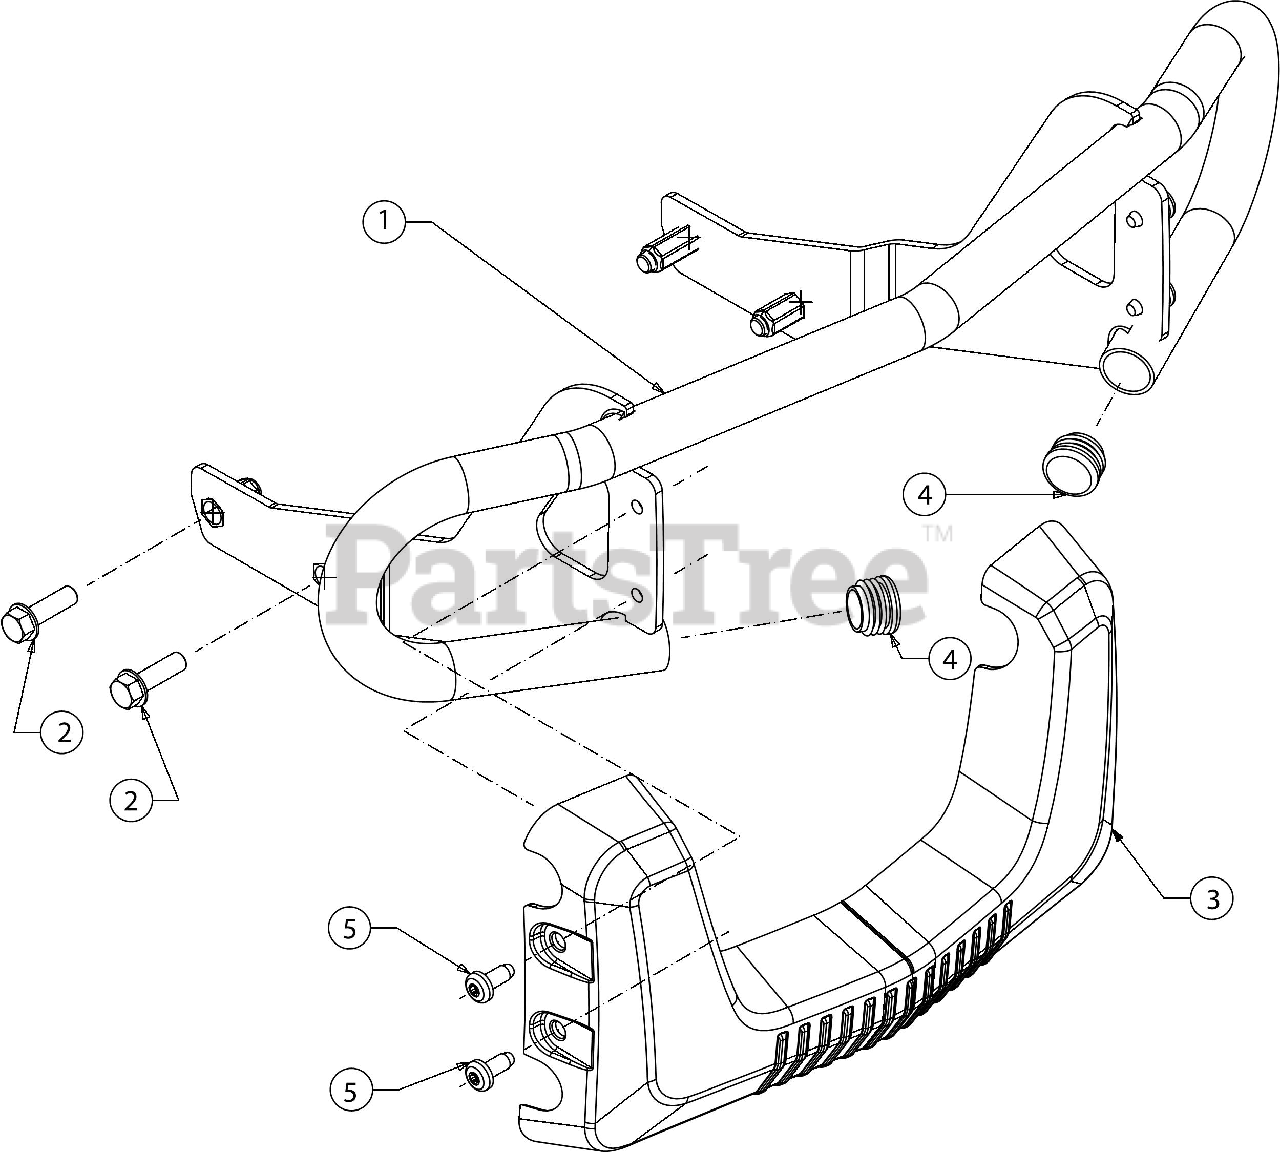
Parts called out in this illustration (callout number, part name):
2	SCREW 3/8-16 x 1.25 GR5
3	BUMPER COVER
4	BUMPER TUBE CAP
5	SCREW 5/16-18 x .750
